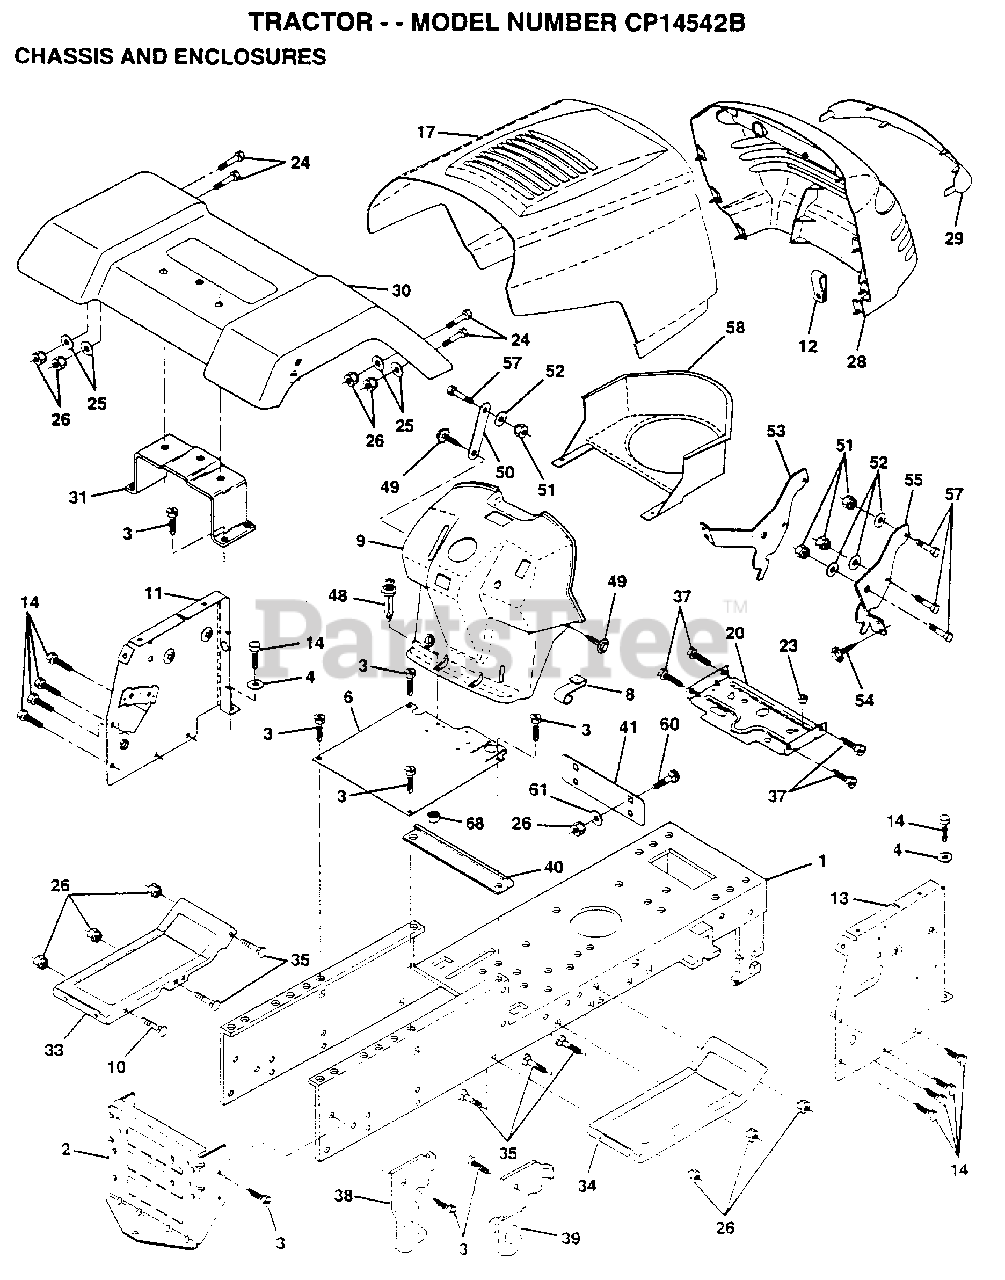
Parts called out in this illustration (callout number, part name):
1	CHASSIS.WLD.11GA
3	SCREW
4	WASHER
8	"CLIP,INSULATOR"
12	CLIP.TINNERMAN
14	SCREW LT
17	HOOD.STL.PRV.LA
20	PLATE.MTG.BTRY.TK
24	BOLT
25	WASHER
26	NUT
29	LENS GRILLE
31	BRACKET SUPT FEND
33	FOOTREST.LH.LT/GT
34	FOOTREST.RH.LT/GT
35	BOLT
37	SCREW
38	BRACKET ASM LH
39	BRACKET ASM RH
40	SPACER FENDER LT
41	PLATE EXTEN FEND
48	RIVET.PUSH.PLATE
49	SCREW HEX CRT
50	BRACE SUPT DASH
51	NUT
52	WASHER
53	BRACKET.GRILLE.LH
55	BRACKET.GRILLE.RH
58	DUCT AIR 12-15H
61	WASHER
68	NUT
